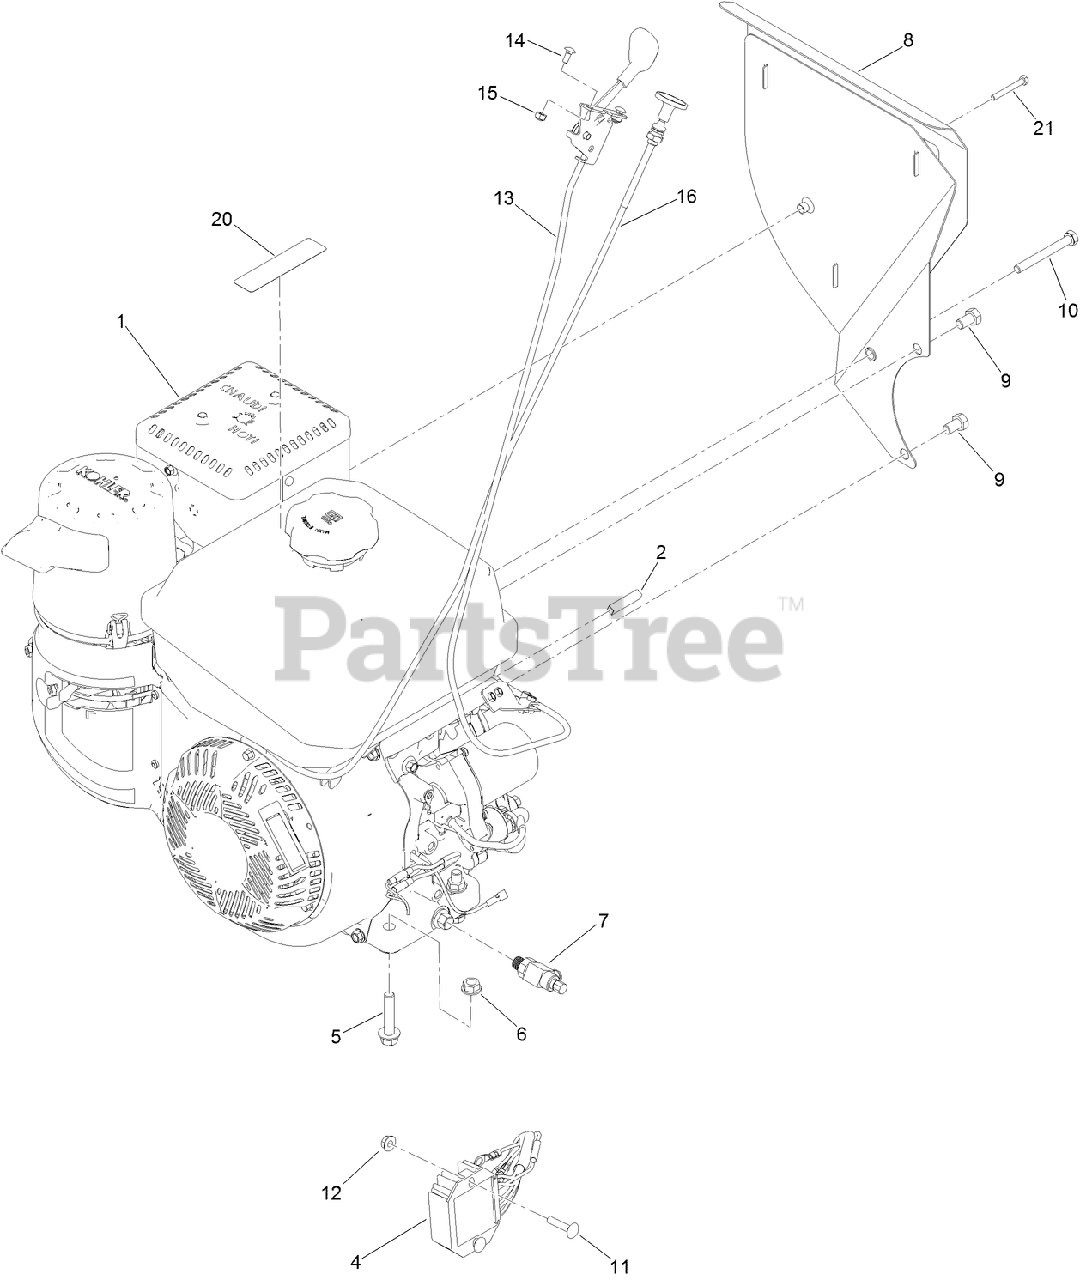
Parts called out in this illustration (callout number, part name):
1	ENGINE-KOHLER, CH395
2	KEY-SQUARE, 7MM
4	Regulator
5	SCREW-HHF
6	NUT-HF
7	VALVE-DRAIN, OIL
8	HEAT SHIELD ASM
9	SCREW-HH
10	SCREW-HH
11	SCREW-CARR
12	NUT-HF
13	CONTROL-THROTTLE
14	BOLT-CARR
15	NUT-LOCK, NI
16	CABLE-CHOKE, PUSH/PULL
20	DECAL-ARRESTOR, SPARK
21	BOLT-M5X0.8MM X 40 MM LONG
